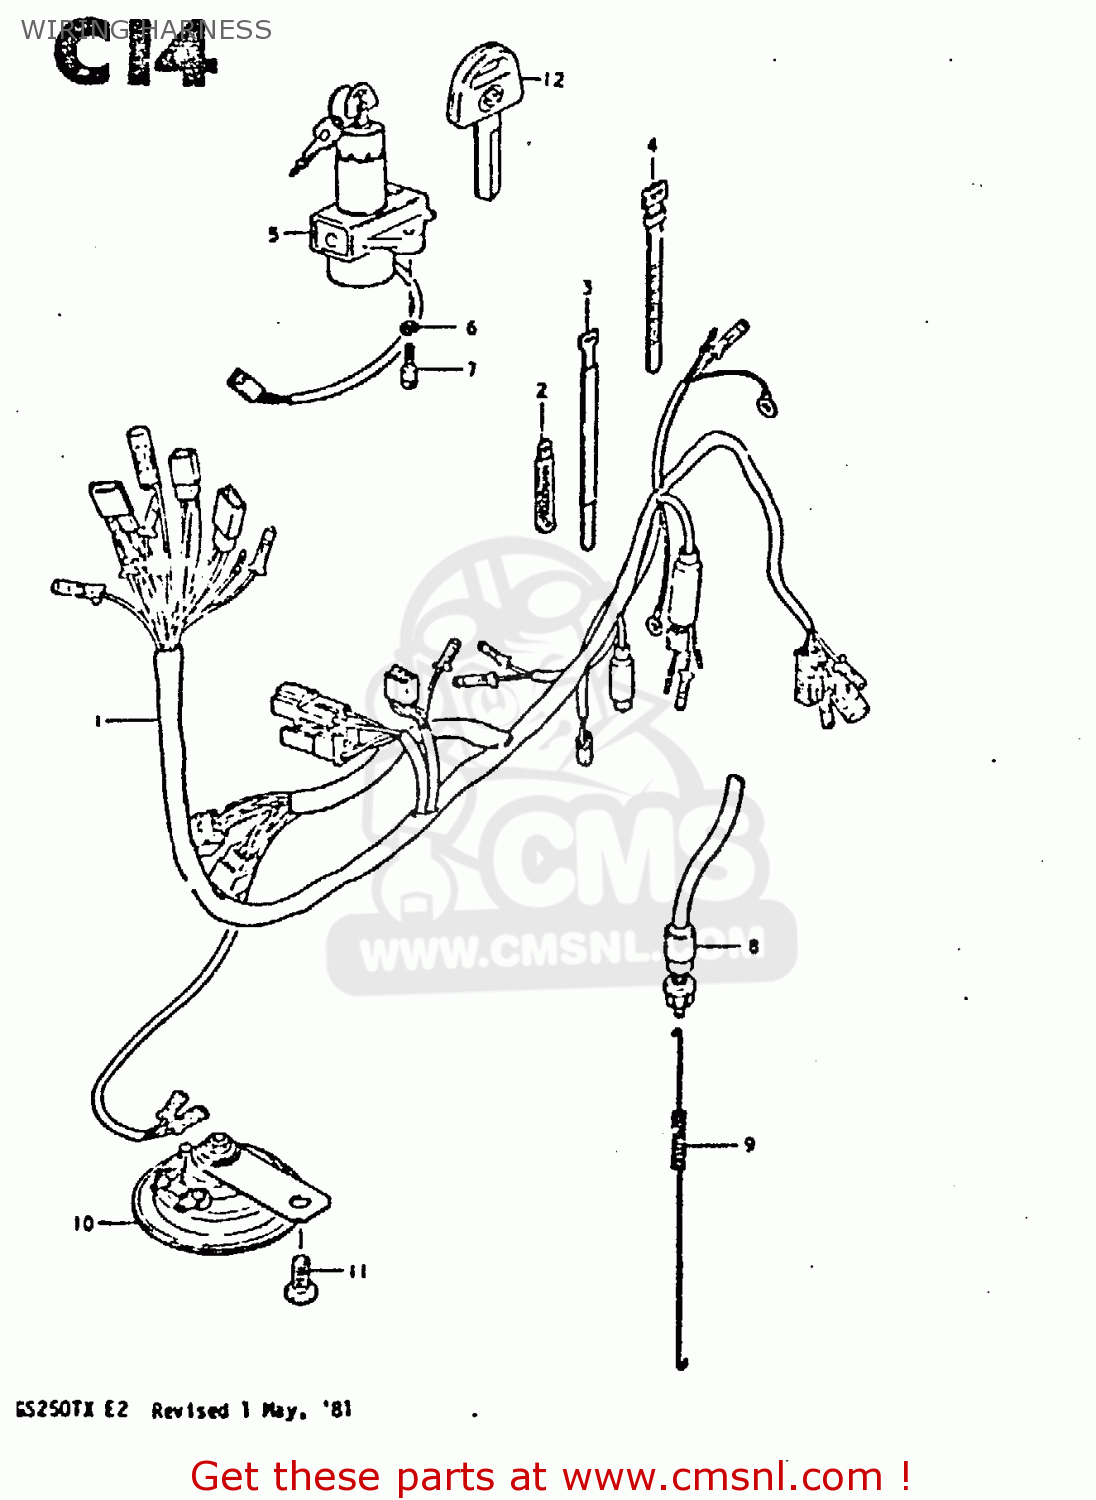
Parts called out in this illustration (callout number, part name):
1	WIRING HARNESS
2	CLAMP
3	CLAMP
4	CLAMP(L:80)
5	SWITCH ASSEMBLY,IGNITION
6	BOLT
7	LOCK WASHER
8	SWITCH ASSEMBLY,STOP LAMP
9	SPRING
10	HORN ASSEMBLY
11	BOLT 8X12
12	KEY,BLANK
